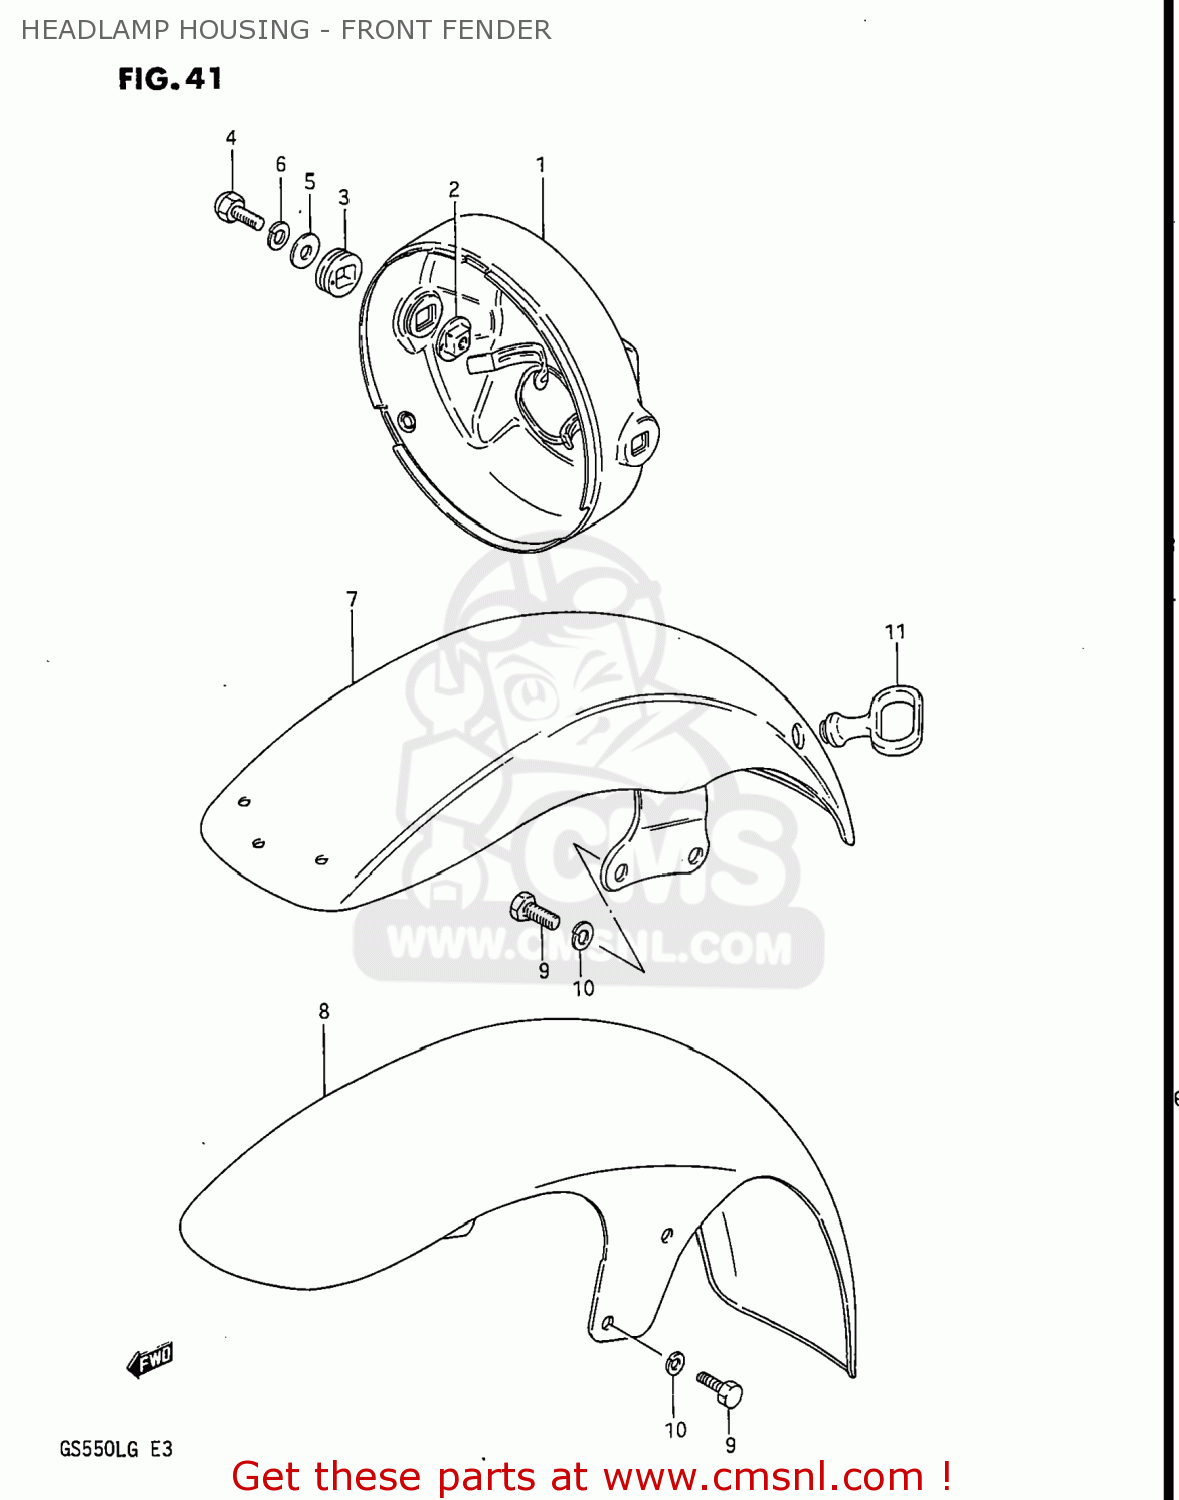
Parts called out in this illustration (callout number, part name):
1	HOUSING ASSEMBLY,HEADLAMP
2	SPACER,HEADLAMP HOUSING
3	CUSHION,HEADLAMP HOUSING
4	BOLT
5	WASHER
6	LOCK WASHER
7	FENDER,FRONT
8	FENDER,FRONT
9	BOLT,8X16
10	LOCK WASHER
11	GUIDE,CABLE
